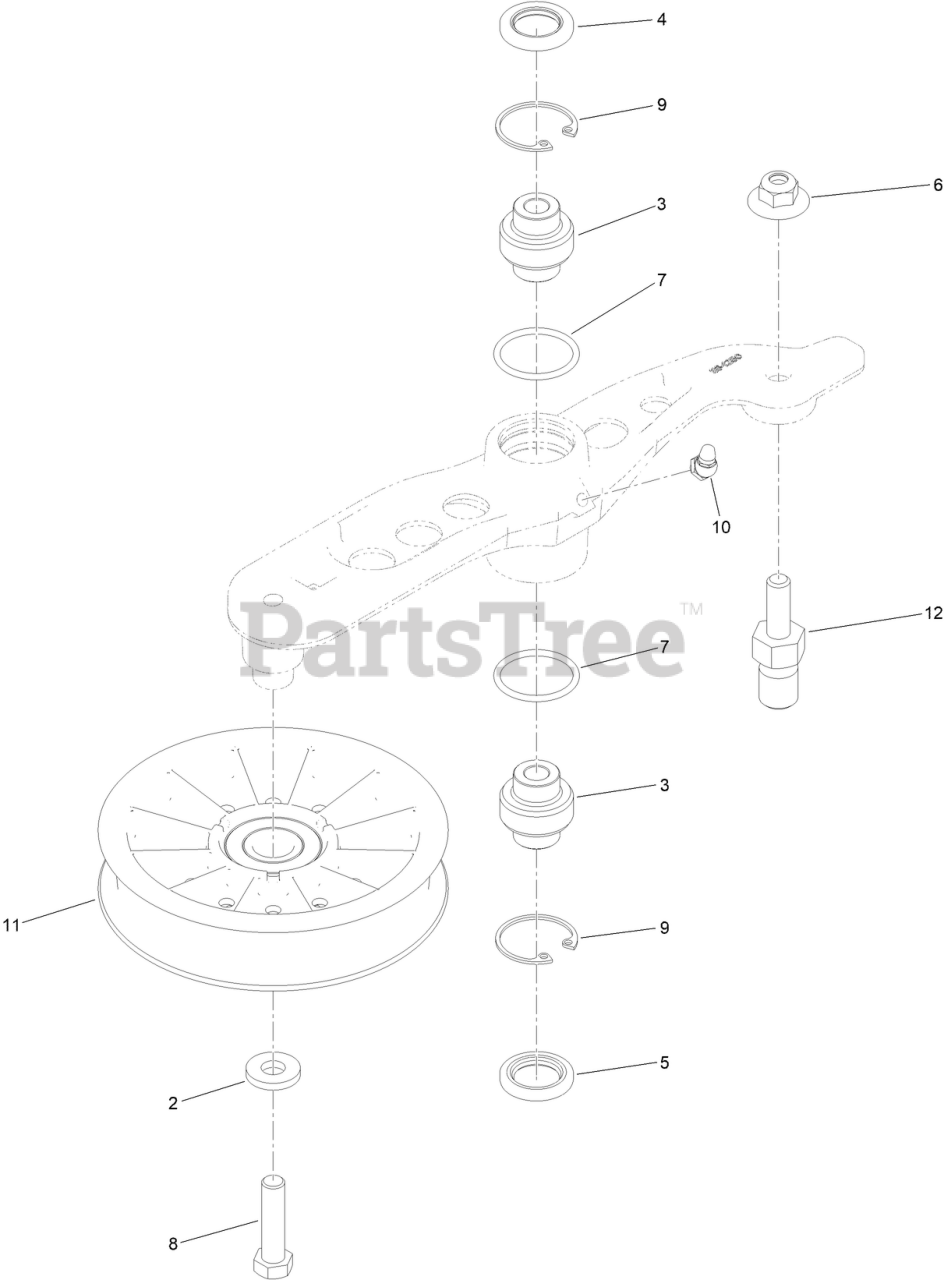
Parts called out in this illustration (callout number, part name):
3	BEARING-SPHERICAL
4	SEAL-LIP, DOUBLE
5	SEAL-LIP, SINGLE
6	Nut-Nyloc 3/8-16 Flg
8	SCREW-HH
9	RING-SNAP
10	FITTING-GREASE
11	PULLEY-IDLER
12	PIN-ANCHOR, SPRING
